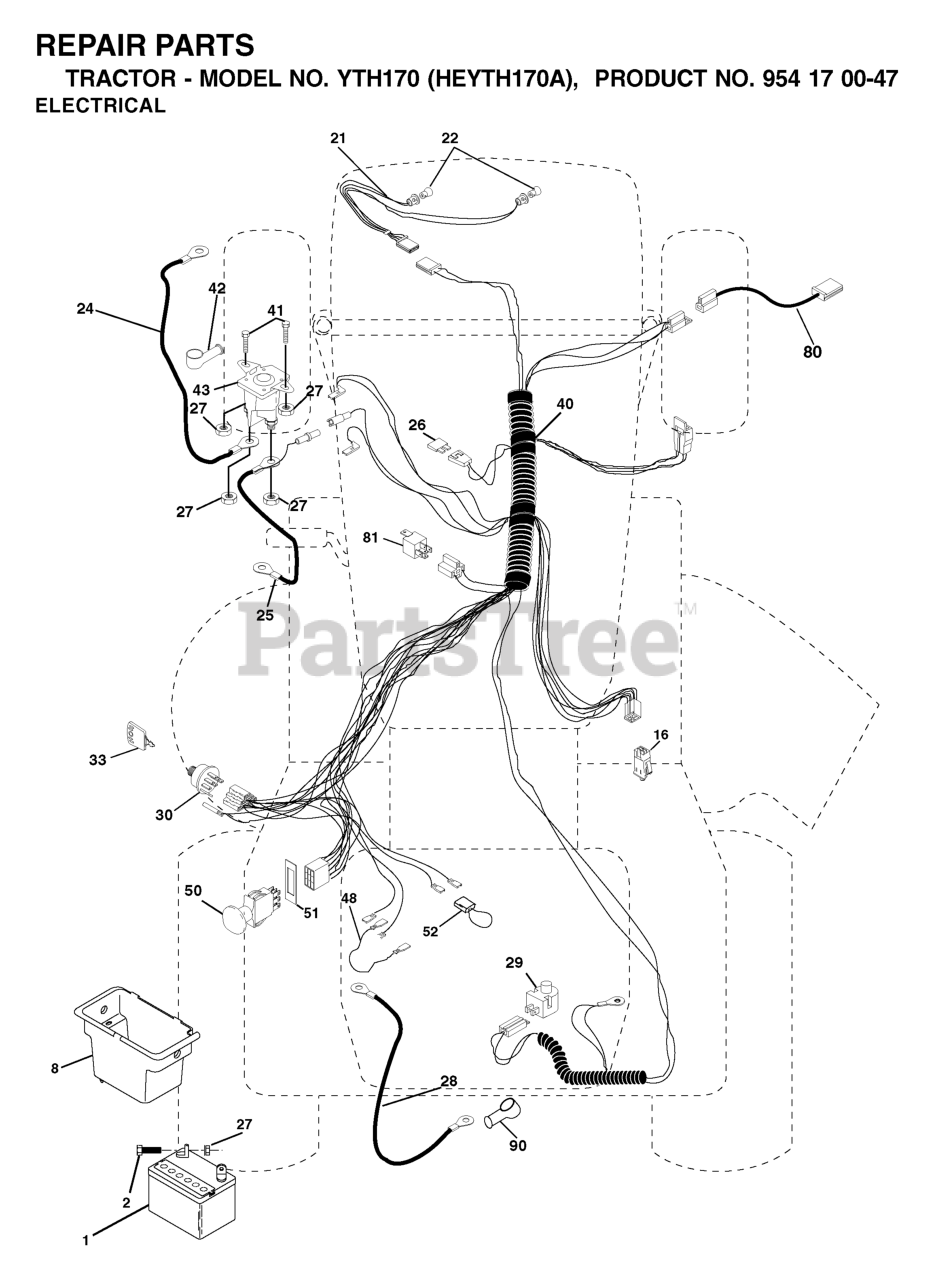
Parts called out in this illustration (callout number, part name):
1	Battery 12 Volt 25 Amp
2	BOLT.HEX.1/4.X.3/4.DICHROMATE
8	BOX.BATTERY.FENDER
16	SWITCH INTERLOOK PUSH-IN
24	BATTERY CABLE GT
25	CABLE BATTERY
26	FUSE 20AMP
27	NUT
28	CABLE T
29	PLUNGER SWITCH (COLOR:OLIVE)
30	IGNITION SWITCH
33	KEY MLD GEN DELTA
40	IGNITION HARNESS
41	BOLT
42	TERMINAL COVER
43	SOLENOID
48	ADAPTER.AMMETER
50	RP.PTO.SWITCH.8 TERMINAL.BLACK
51	FRAME RETAINING RING
52	WIRE PROTECTION LOOP
80	HARNESS, CLUTCH
81	RELAY.ASSY.T
89	COVER TERMINAL
